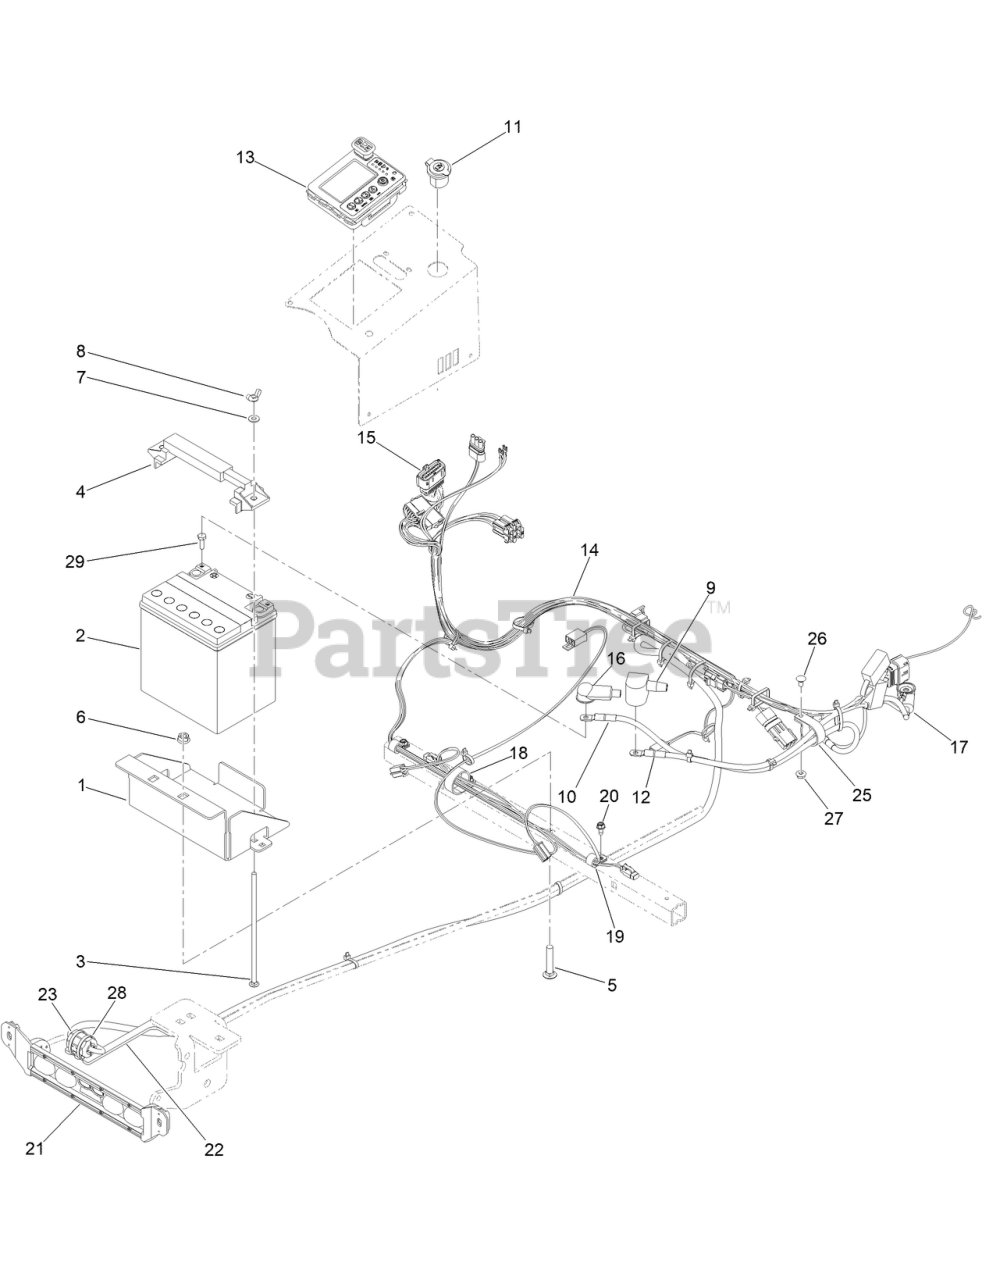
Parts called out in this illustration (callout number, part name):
1	MWR BATTERY BOX BLACK
2	BATTERY - ETX30LA - 400CCA
3	1/4IN-20X8IN GR5 CARRIAGE BOLT
4	BATTERY HOLD DOWN
5	SCREW-CARR
6	3/8-16 HEX FLANGE NUT W/SERR ZINC YELLOW
7	WASHER-FLAT
8	NUT-WING
9	INSULATOR-BATTERY
10	MWR NEGATIVE CABLE 28
11	12 VOLT AUXILLIARY PLUG
12	MWR POSITIVE BATTERY CABLE 25IN
13	CONSOLE-CONTROL
14	BIG BLOCK 40HP OIL GUARD TWIN TK HARNESS
15	HARNESS-JUMPER
16	STRAIGHT INSULATING TERMINAL COVER
17	3.15 LGTH STRAIGHT INSUL TERM COVER RED
18	3/4 EPDM CUSHION CLAMP
19	CLAMP-R
20	SCREW-HWH
21	FULL BEAM WITH LIGHTED HELMET LIGHT BAR
22	FAIR-RITE BRACKET PAINTED
23	FAIR-RITE ROUND CABLE SNAP-IT SIZE B
25	1-1/4IN CUSHIONED LOOP CLAMP BLACK
26	SCREW-CARR
27	1/4-20 HEX FLANGE NUT
28	TIE-CABLE
29	SCREW-HH
